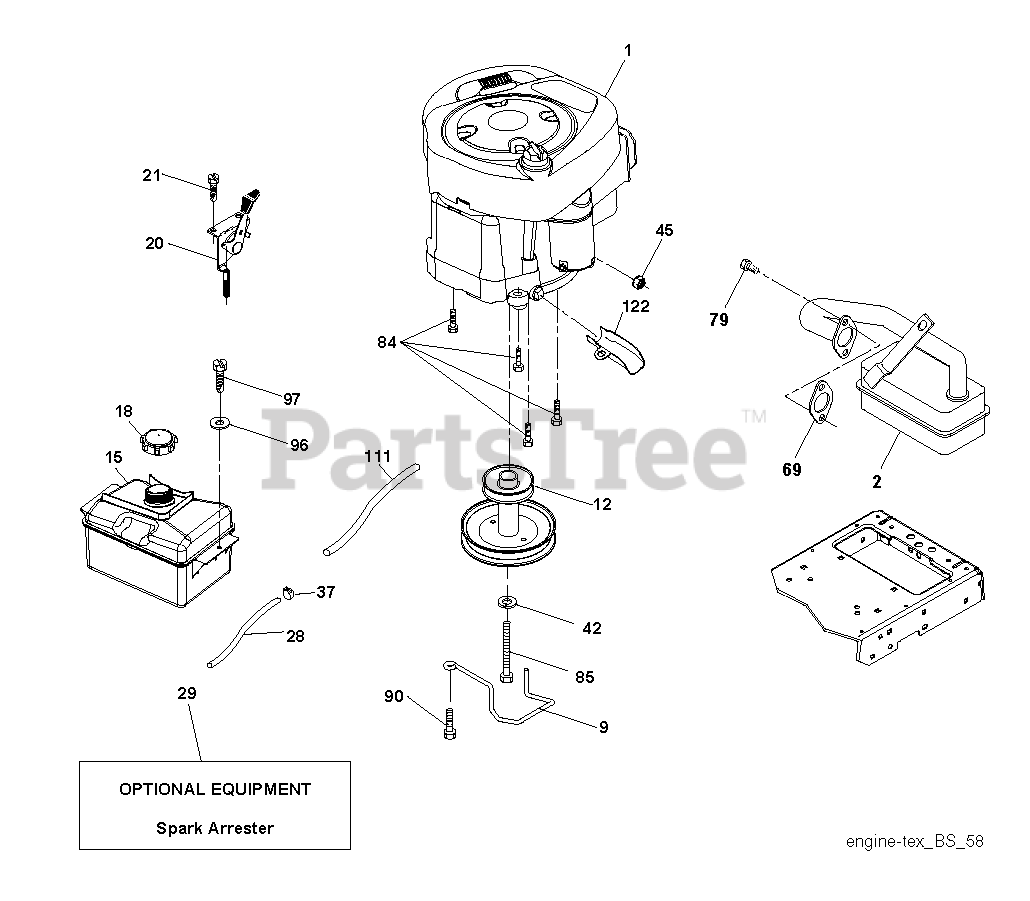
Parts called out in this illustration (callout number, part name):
1	Husqvarna TBD
2	MUFFLER.LT.BRIGGS.14HP.IC/OHV
9	KEEPER.BELT.ENGINE.3.25 (3 2)
12	PULLEY.ENG.CL.MECH.SLVR.LT/YT
15	TANK.ASM.1.5GAL.FRT.W/CAP.EPA
18	CAP.2.25'.VENTED.TETHER .EPA
20	CONTROL.TH/CK.C.
21	SCREW.#10 X 0.750.BOS
28	LINE.FUEL.20"FRONT.EMI
29	KIT.SPARK ARRESTOR 794945 B&S
37	HOSE CLAMP
42	LOCKWASHER
45	NUT
79	SCREW.3/8-16
84	SCREW.3/8-16
85	BOLT HEX 7/16-20X4-1/4"
90	SCREW 3/8-16X1
97	SCREW HEXWSHR 1/4-20X3/4
111	RP PURGE LINE
122	EXTENSION DRAIN OIL
